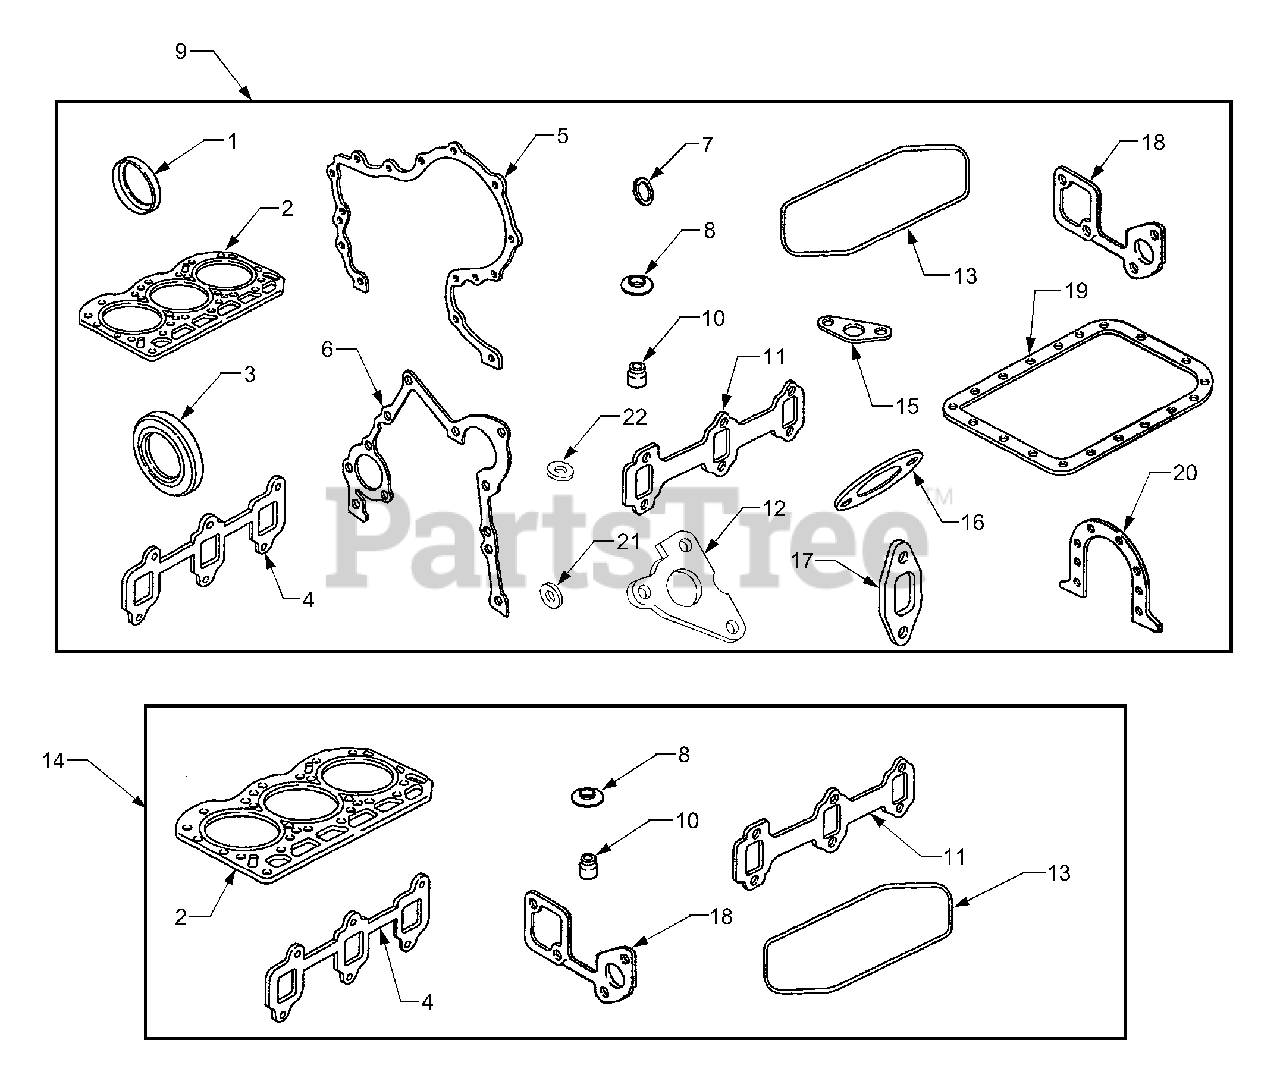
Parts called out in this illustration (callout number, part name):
1	Seal, Oil
2	Gasket, Cylinder Head
3	Seal, Oil
4	Gasket, Intake
5	Gasket, Gear Cover
6	Gasket, Gear Cover
7	Washer, Sealing
8	Washer, Sealing
9	Gasket Set
10	Seal, Valve
11	Gasket, Exhaust
12	Gasket, Exhaust
13	Gasket, Rocker Cover
14	Kit, Valve Overhaul
15	Gasket, Oil Pump Screen
16	Gasket, Outlet
17	Gasket, Inlet Housing
18	Gasket, Water Pump
19	Gasket, Oil Pan
20	Gasket, Retainer
21	Washer, Sealing (Oil Inlet Pipe)
22	Washer, Sealing (Oil Inlet Pipe)
